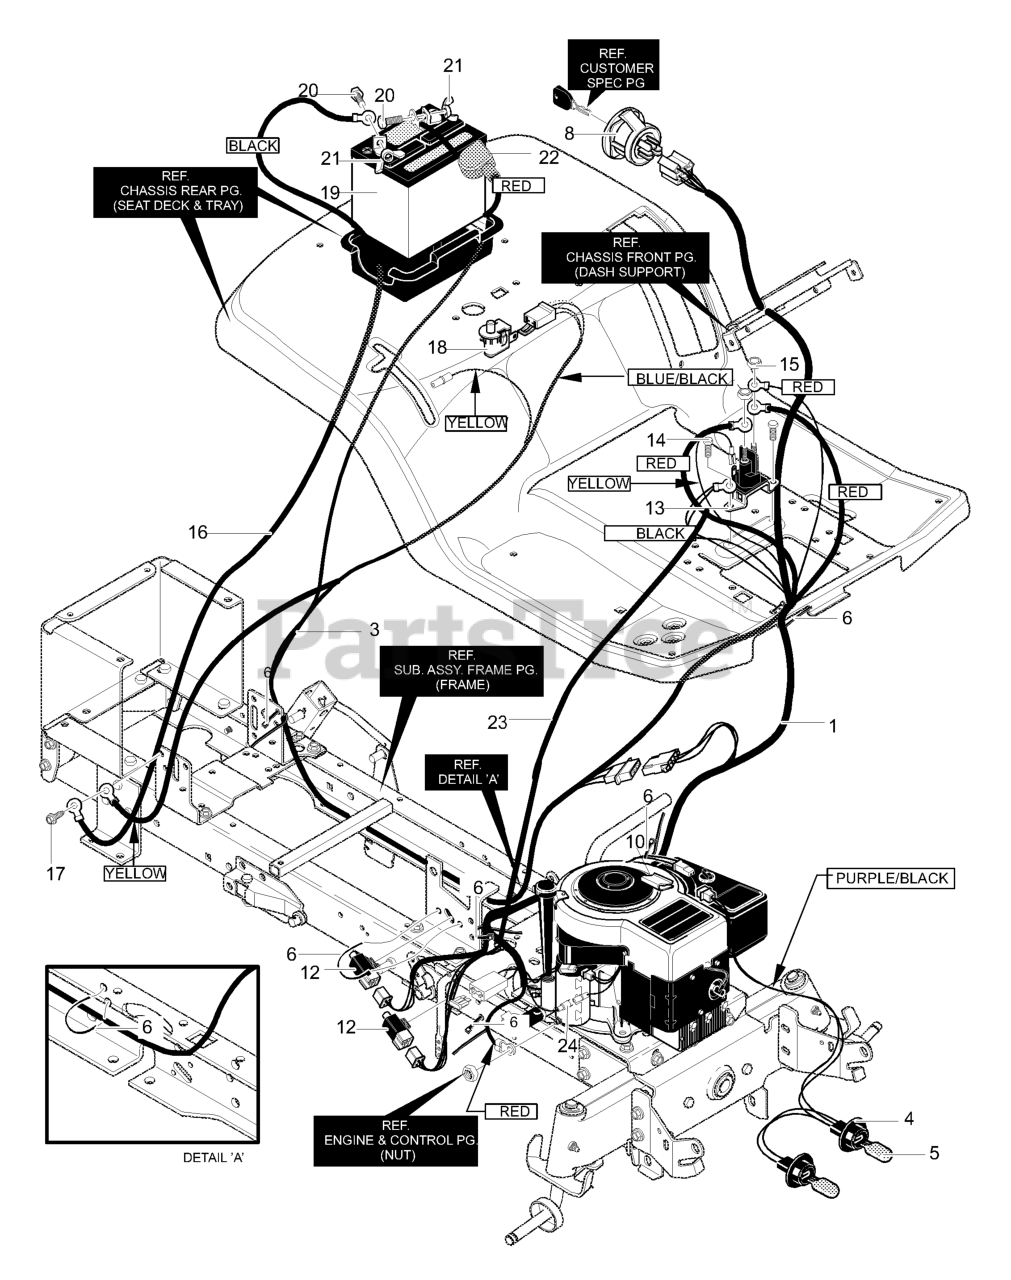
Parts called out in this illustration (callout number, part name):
1	Wire Harness
3	Wire Harness, Rear
4	Wire Harness *
5	Bulb, Headlamp
6	Cable Tie
8	Switch, Ignition
10	Wire Clip, Adhesive
12	Switch, Limit
13	Solenoid
14	Screw 1/4x.50
15	Nut, 1/4-20
16	Ground Wire
17	Screw, 1/4x.75
18	Seat Switch
19	Battery 5 Plate
20	Bolt, 1/4-20x.63
21	Wing Nut
22	Battery Boot
23	Wire, Lead Solenoid to Starter
24	Harness Adapter
